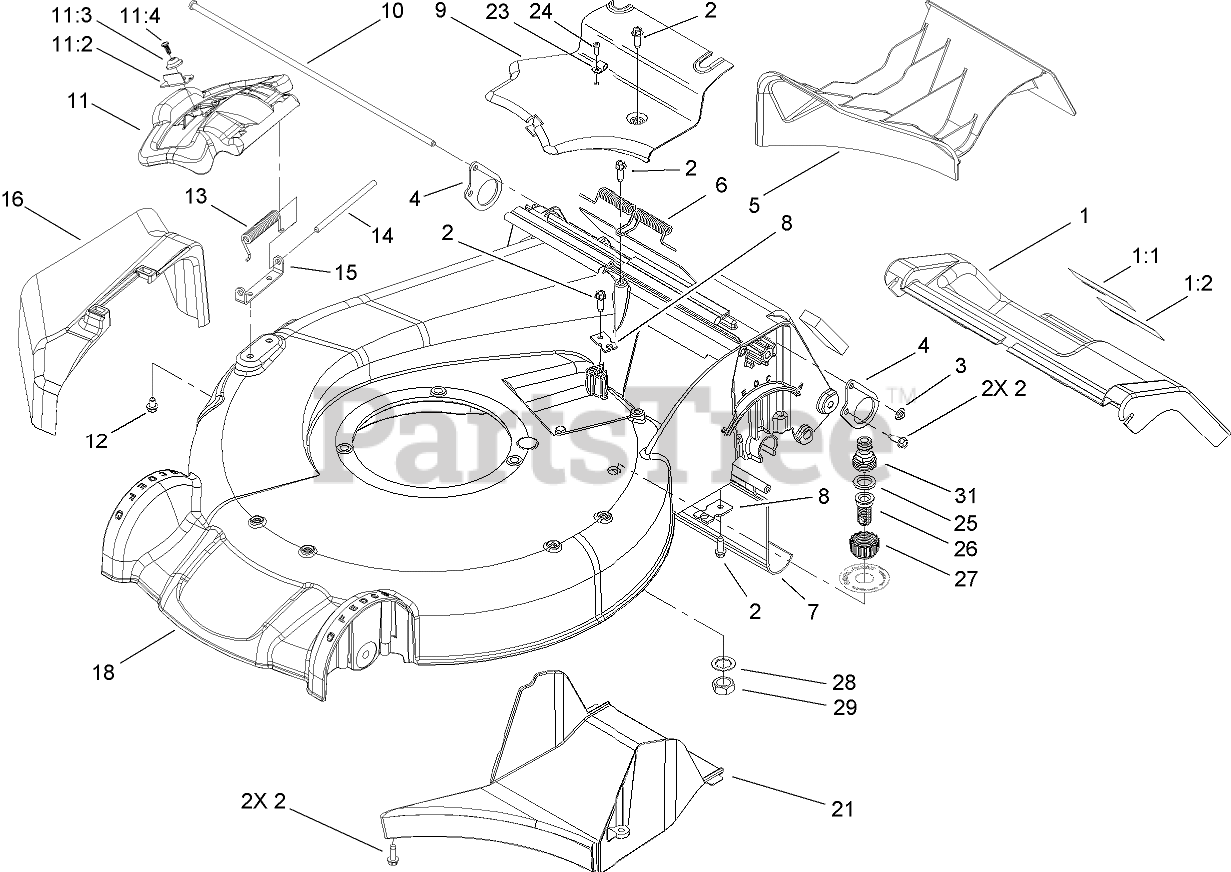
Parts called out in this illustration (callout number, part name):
1	DOOR-SERVICE
1:1	DECAL-WARNING
1:2	DECAL-WARNING
2	SCREW-HWHTF
3	NUT-SPEED
4	PLATE-SUPPORT, DOOR
5	MULCH PLUG ASM
6	Spring-Door, Rear
7	SHIELD-TRAILING
8	BRACKET-CABLE, TRACTION
9	COVER-BELT
10	ROD-SUPPORT, DOOR
11	DISCHARGE DOOR ASM
11:2	LATCH-DOOR
11:3	CAP-DOOR
11:4	SCREW-PLASTITE
12	SCREW-HWH
13	SPRING-TORSION
14	ROD-COVER
15	BRACKET-COVER
16	CHUTE-DISCHARGE, SIDE
18	HOUSING ASM
21	TUNNEL-DISCHARGE
23	CLAMP
25	WASHER-SEAL, WASHOUT PORT
26	PORT-WASHOUT
27	COUPLING-HOSE, WASHOUT PORT
28	WASHER-TOOTH, INTERNAL
29	NUT-JAM
31	ADAPTER-CONNECT, QUICK
